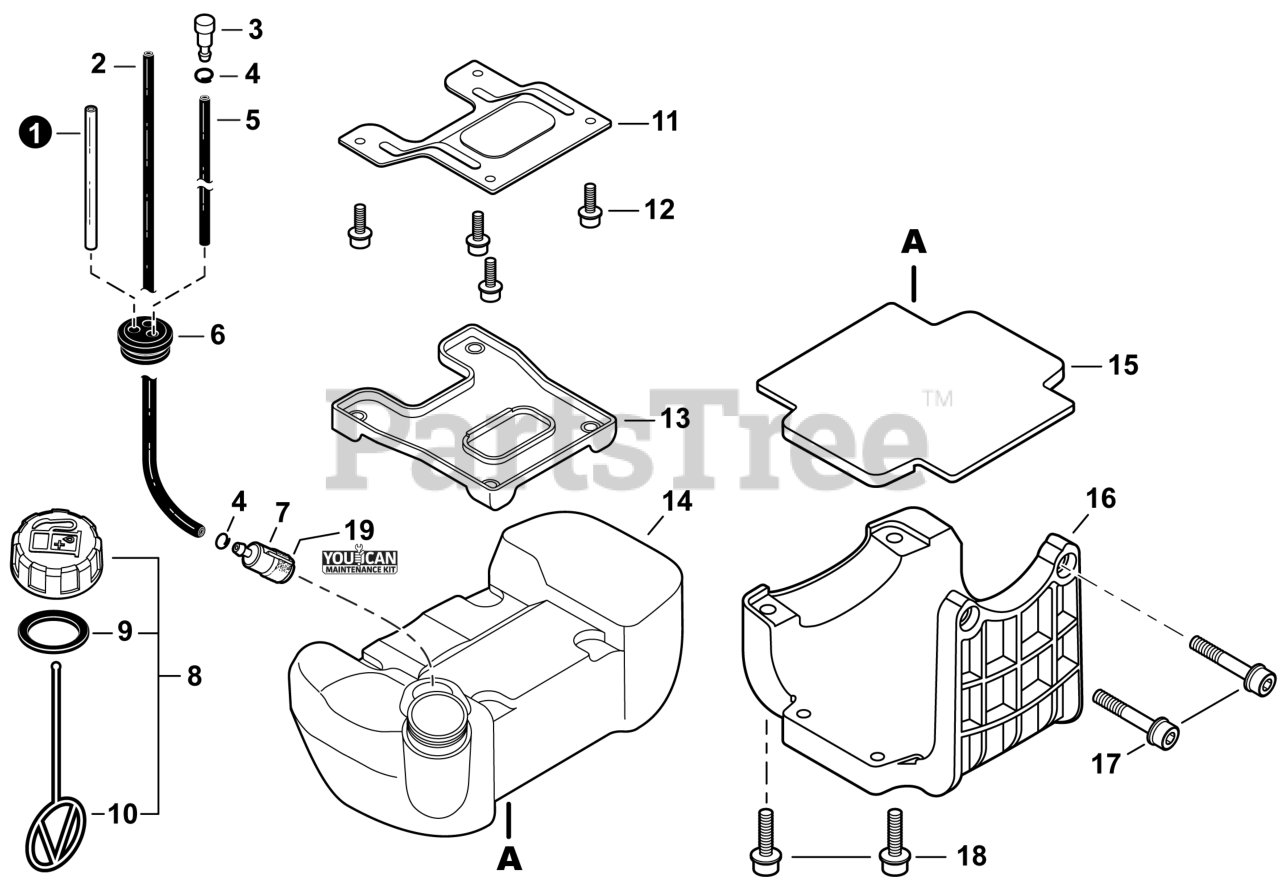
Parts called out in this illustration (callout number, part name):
1	PIPE, FUEL 3x6x120 CLEAR
2	PIPE, FUEL 3x6x230
3	VENT ASSY
4	CLIP 6.5 MM
5	PIPE, FUEL 3x6x120 BLACK
6	GROMMET, FUEL
7	FILTER, FUEL
8	CAP ASSY, FUEL
9	GASKET, FUEL CAP
10	CONNECTOR, CAP L= 100 MM
11	BRACKET, FUEL TANK
12	BOLT 5x12
13	CUSHION, UPPER
14	TANK, FUEL
15	CUSHION, FUEL TANK
16	GUARD, FUEL TANK
17	BOLT 5x25
18	BOLT 5x20
19	TUNE-UP KIT - YOUCAN?
